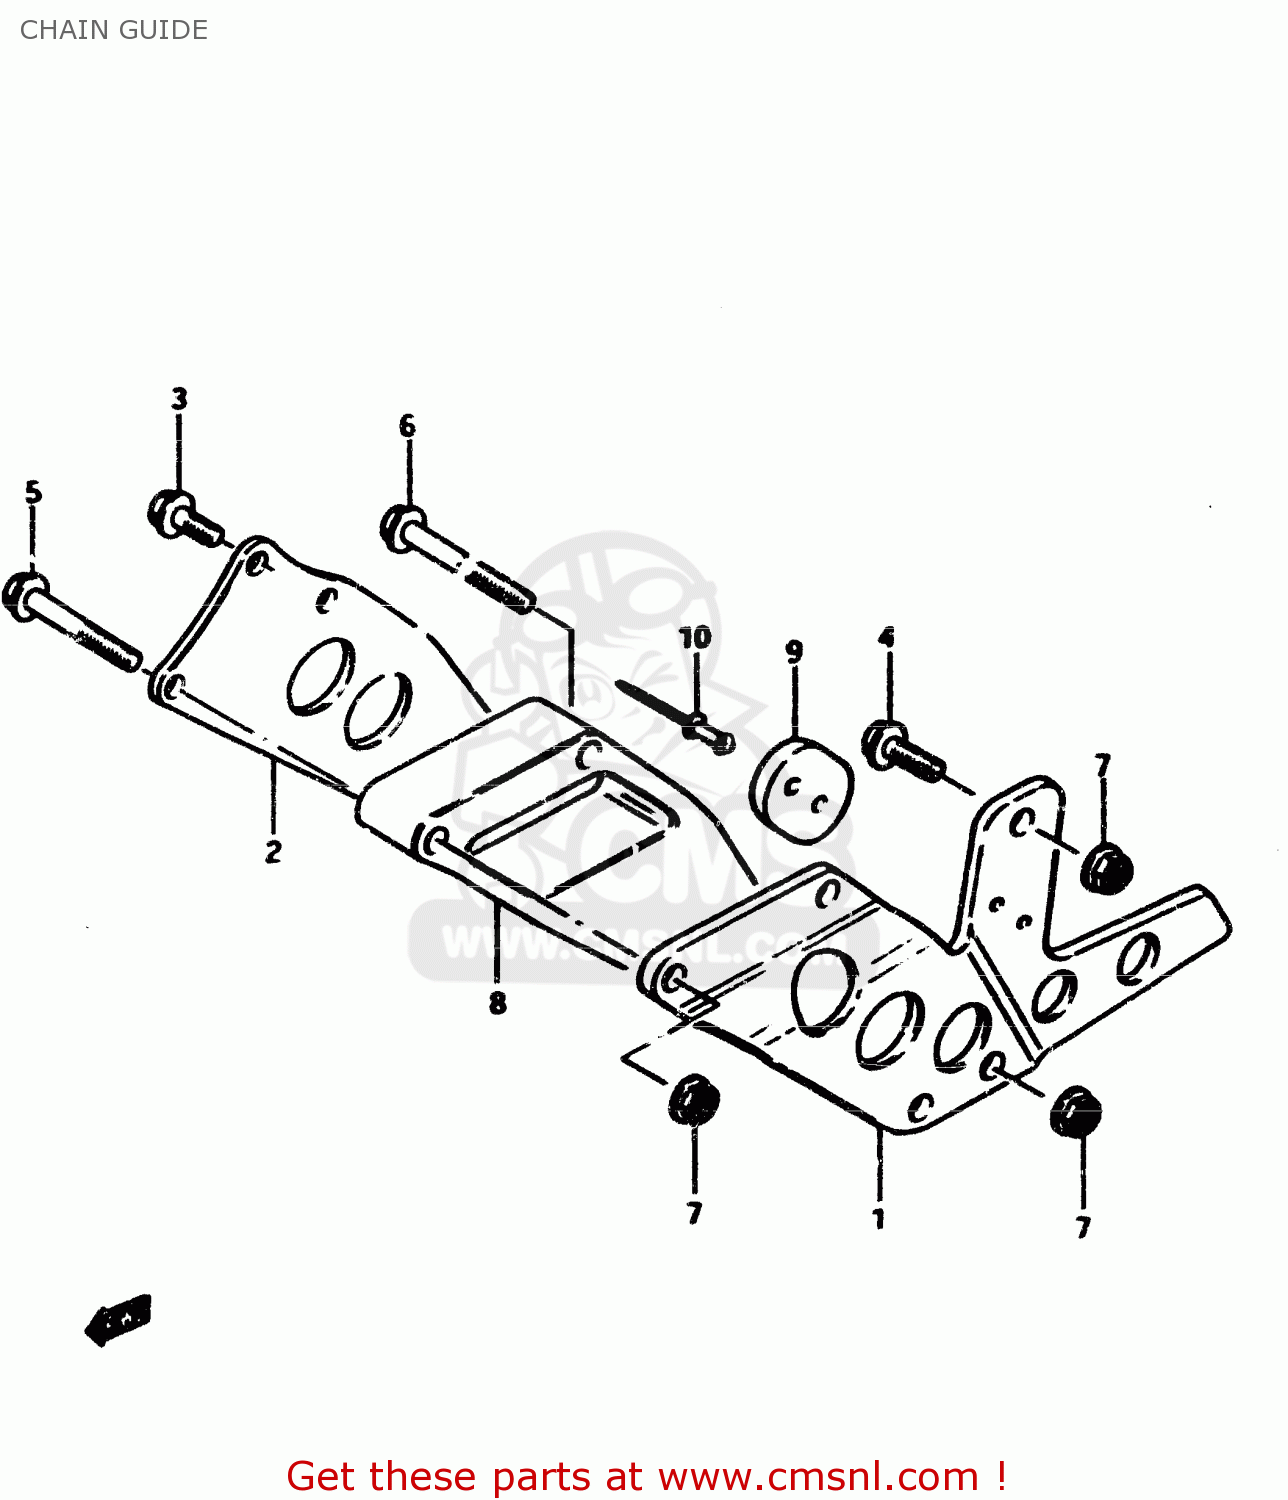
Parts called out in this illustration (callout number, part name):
1	PLATE,CHAIN GUIDE,OUTER
2	PLATE,CHAIN GUIDE,INNER
3	BOLT
4	BOLT,REAR
5	BOLT
6	BOLT,UNDER
7	NUT
8	DEFENSE,CHAIN GUIDE
9	PAD,CHAIN GUIDE
10	RIVET
